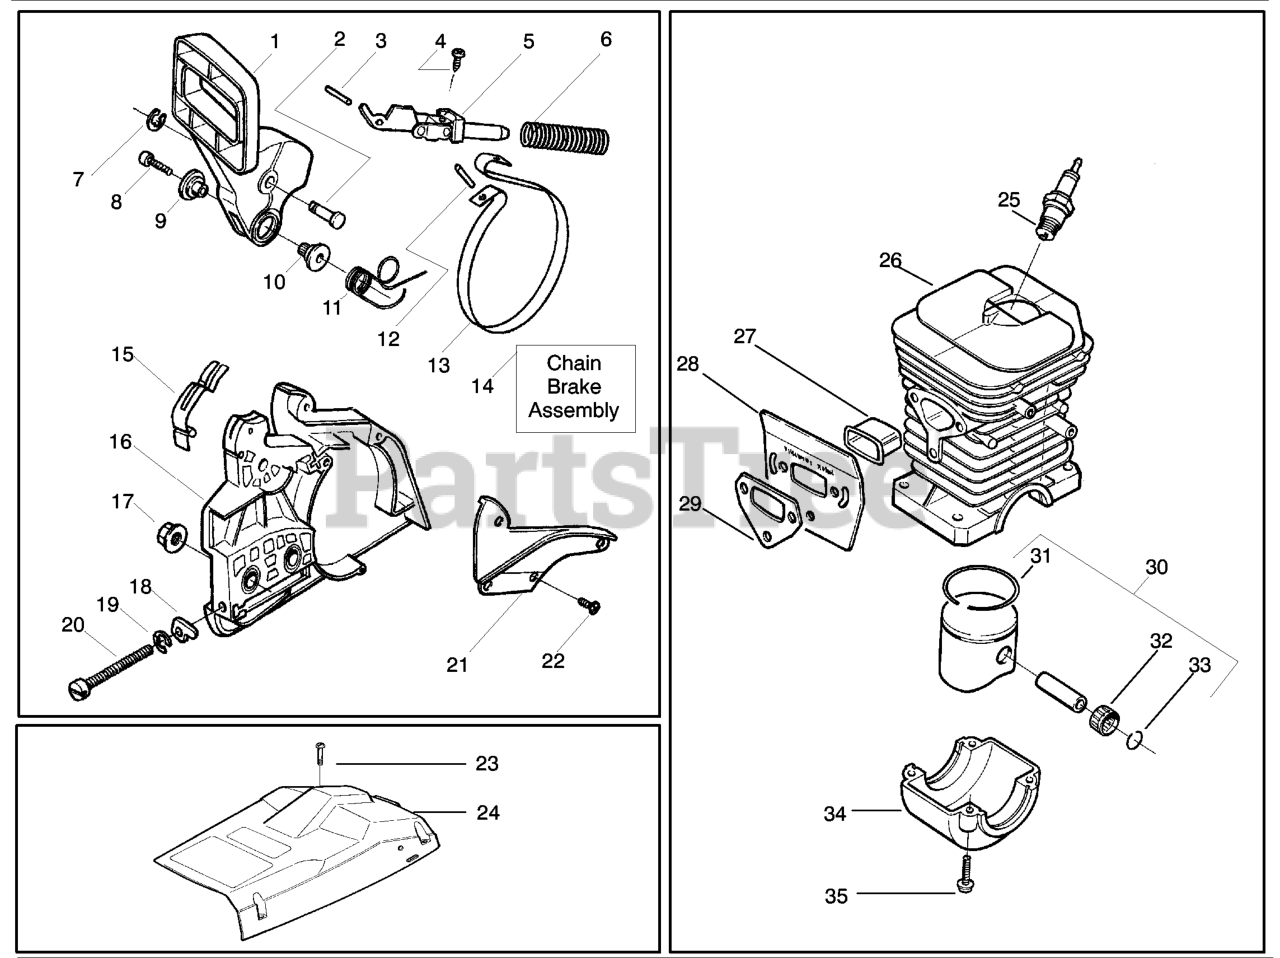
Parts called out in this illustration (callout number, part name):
4	SCREW
5	FRONT LINK ASSY
6	%COMPRESSION SPRING
9	JOURNAL, RIGHT
10	SHAFT PIVOT
11	SPRING,BRK HDL 36/41
13	BRAKE BAND
14	CHAIN BRAKE ASM.
15	SPRING-POSITION
16	CLUTCH COVER
18	ADJUST PIN,BAR 36/41
20	BAR ADJUSTING SCREW
21	CHAIN BRAKE COVER
22	SCREW
24	CYLINDER SHIELD ASSY
25	Spark Plug (RCJ-7Y)
26	Kit-Cylinder
27	HEAT INSULATOR
28	MUFFLER PLATE
30	Piston Kit
30	PISTON KIT/136
30	KIT-PISTON
31	Piston Ring
31	PISTON RING 36
31	PISTON RING HV41
32	Piston Pin Bearing
33	C-CLIP,PSTN PIN 36/41
34	Cap-Crankcase
35	SCREW-M5-0.8 X 25MM(TAP)
